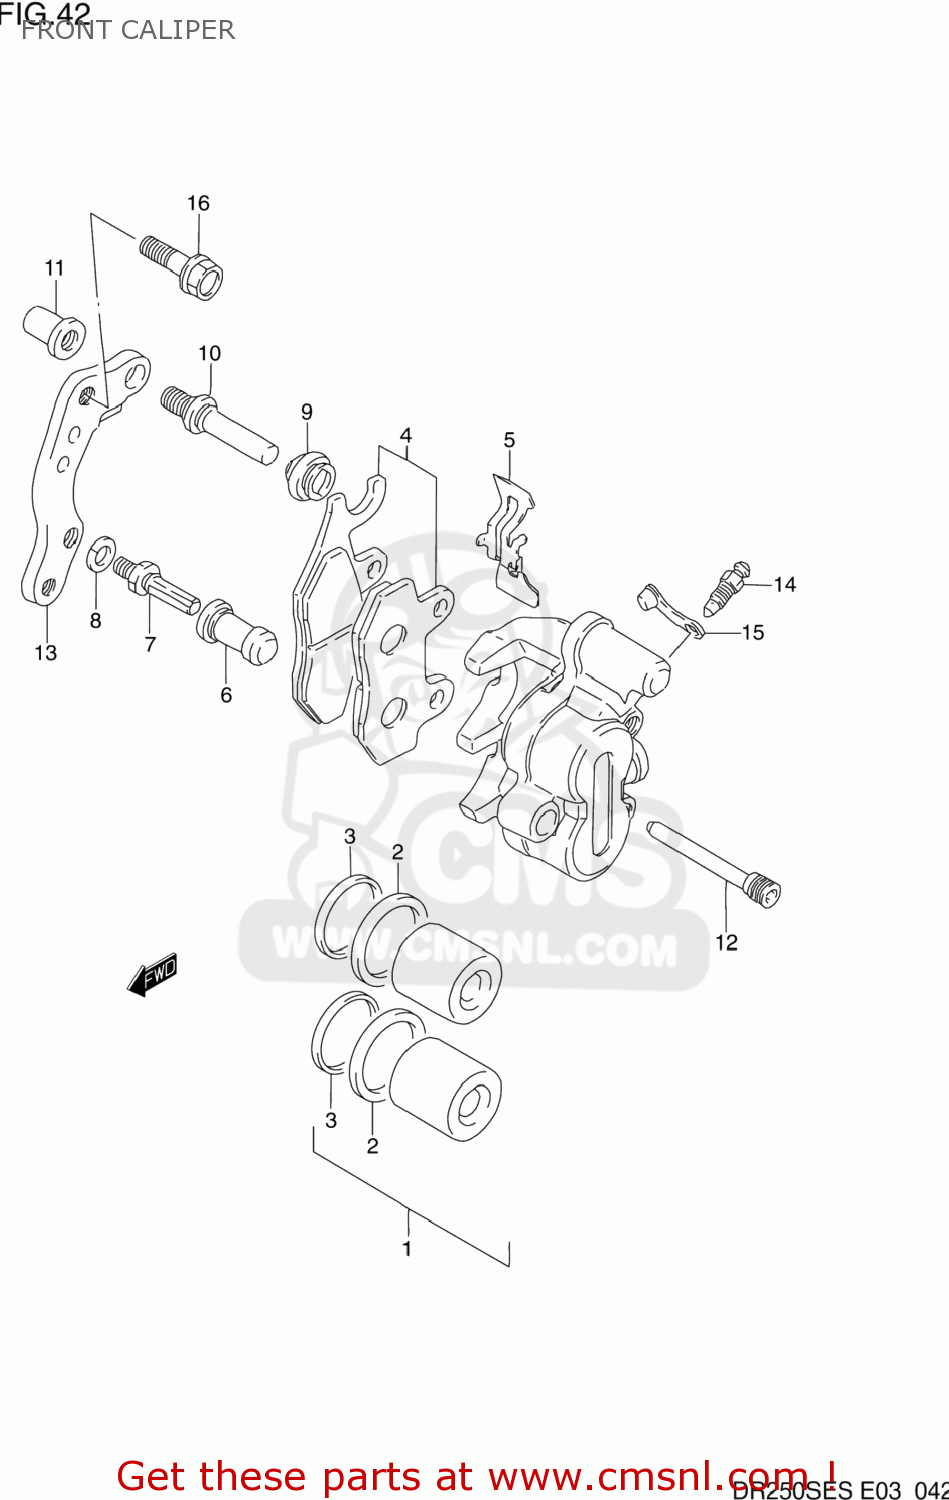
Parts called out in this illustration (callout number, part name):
1	PISTON SET
2	SEAL,PISTON
3	SEAL,DUST
4	PAD SET (NAS)
5	SPRING
6	BOOT
7	BOLT,PIN
8	WASHER,WAVE
9	BOOT
10	PIN,SLIDE
11	NUT
12	PIN,HOLDER
13	BRACKET
14	BLEEDER
15	CAP,BLEEDER
16	BOLT(8X24)
